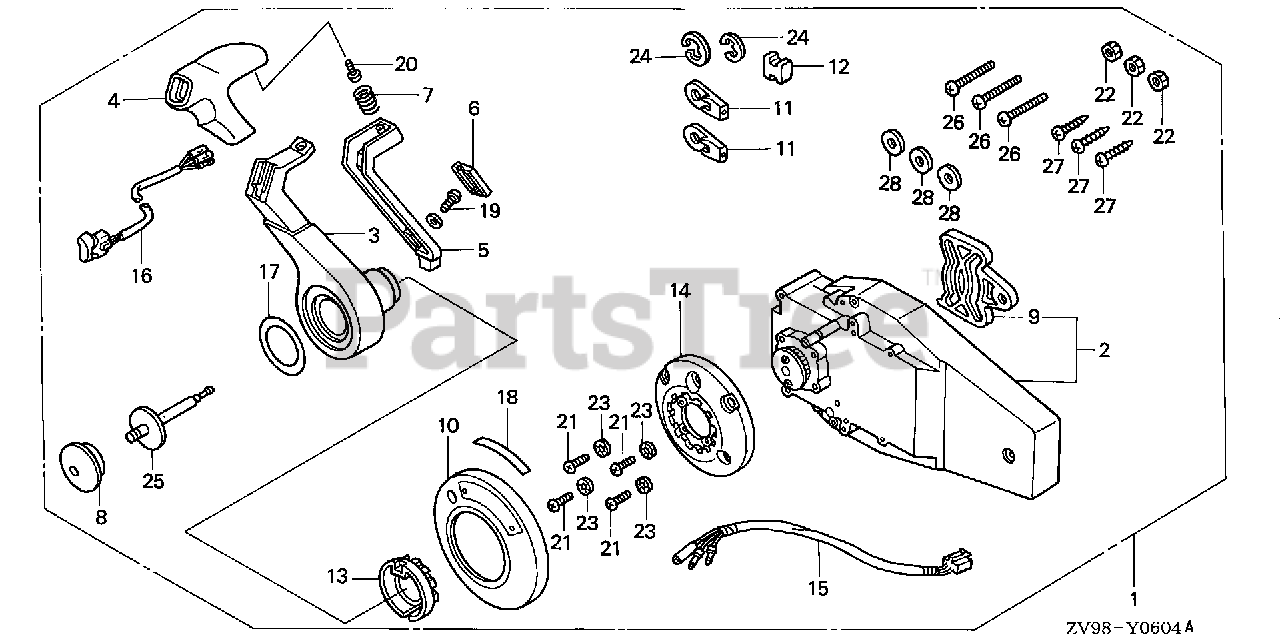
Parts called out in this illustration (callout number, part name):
1	BOX KIT, REMOTE CONTROL (FLUSH MOUNT)(R)
2	HOUSING ASSY., R. (INNER) (FLUSH MOUNT)
3	HANDLE, REMOTE CONTROL
4	COVER, GRIP
5	ARM, NEUTRAL LOCK
6	COVER, LOCK ARM
7	SPRING, NEUTRAL LOCK ARM
8	BUTTON, THROTTLE
9	PLATE, DWELL
10	COVER ASSY.
11	TERMINAL, CABLE
12	SPACER, CABLE CLAMP
13	HOLDER, NEUTRAL LOCK
14	BASE
15	SUB-HARNESS ASSY., POWER TRIM-TILT (C)
16	SWITCH ASSY., POWER TRIM-TILT (C)
17	MARK, HANDLE FLUSH MOUNT (HONDA MARINE)
17	MARK, HANDLE FLUSH MOUNT
18	MARK, FLUSH MOUNT
19	SCREW, PAN (5X16)
20	SCREW, TRUSS (4X12)
21	SCREW, PAN (5X30)
22	NUT, HEX. (6MM)
23	WASHER, LOCK (5MM)
24	E-RING (6MM)
25	SHAFT, THROTTLE BUTTON
26	SCREW, PAN (6X35)
27	SCREW, TAPPING (6X30)
28	WASHER, PLAIN (6MM)
